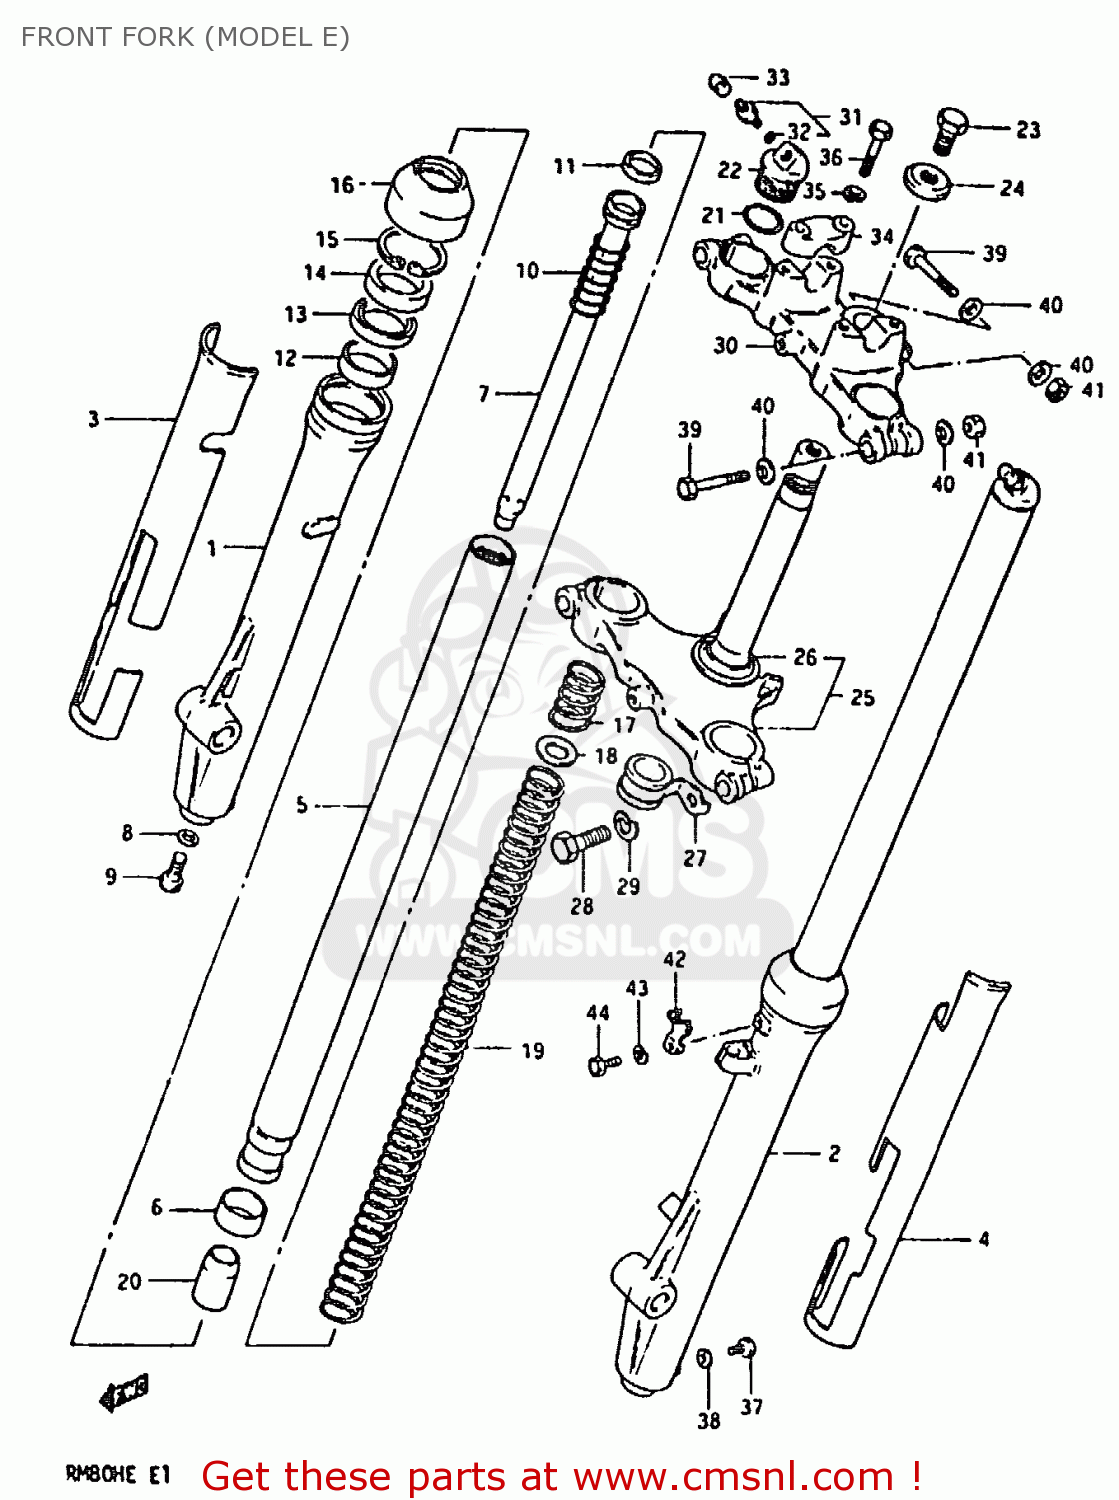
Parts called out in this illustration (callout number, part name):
1	TUBE, OUTER RH
2	TUBE, OUTER LH
3	PROTECTOR, RH
4	PROTECTOR, LH
5	TUBE, INNER
6	PISTON
7	PIPE, SEAT
8	GASKET (NAS)
9	BOLT(8X27)
10	SPRING,FORK REBOUND
11	RING,PISTON
12	BUSH,GUIDE
13	SPACER,SEAL
14	OIL SEAL,FRONT FORK
15	CIRCLIP,FORK OIL SEAL
16	DUST SEAL,FR FORK
17	SPRING A
18	SPRING,JOINT
19	SPRING B
20	PIECE, OIL LOCK
21	O RING
22	BOLT
23	BOLT
24	WASHER
25	STEM, STEERING (PEARL METALLIC)
26	RACE,STEERING OUTER LWR
27	CLIP
28	BOLT
29	WASHER,LOCK 12
30	STEM HEAD, STEERING
31	VALVE,AIR
32	O-RING
33	CAP,VALVE AIR
34	HOLDER,HANDLEBAR
35	LOCK WASHER
36	BOLT
37	BOLT(6X8)
38	GASKET,DRAIN,PLUG (NAS)
39	BOLT
40	WASHER
41	NUT
42	HOLDER
43	LOCK WASHER
44	BOLT
